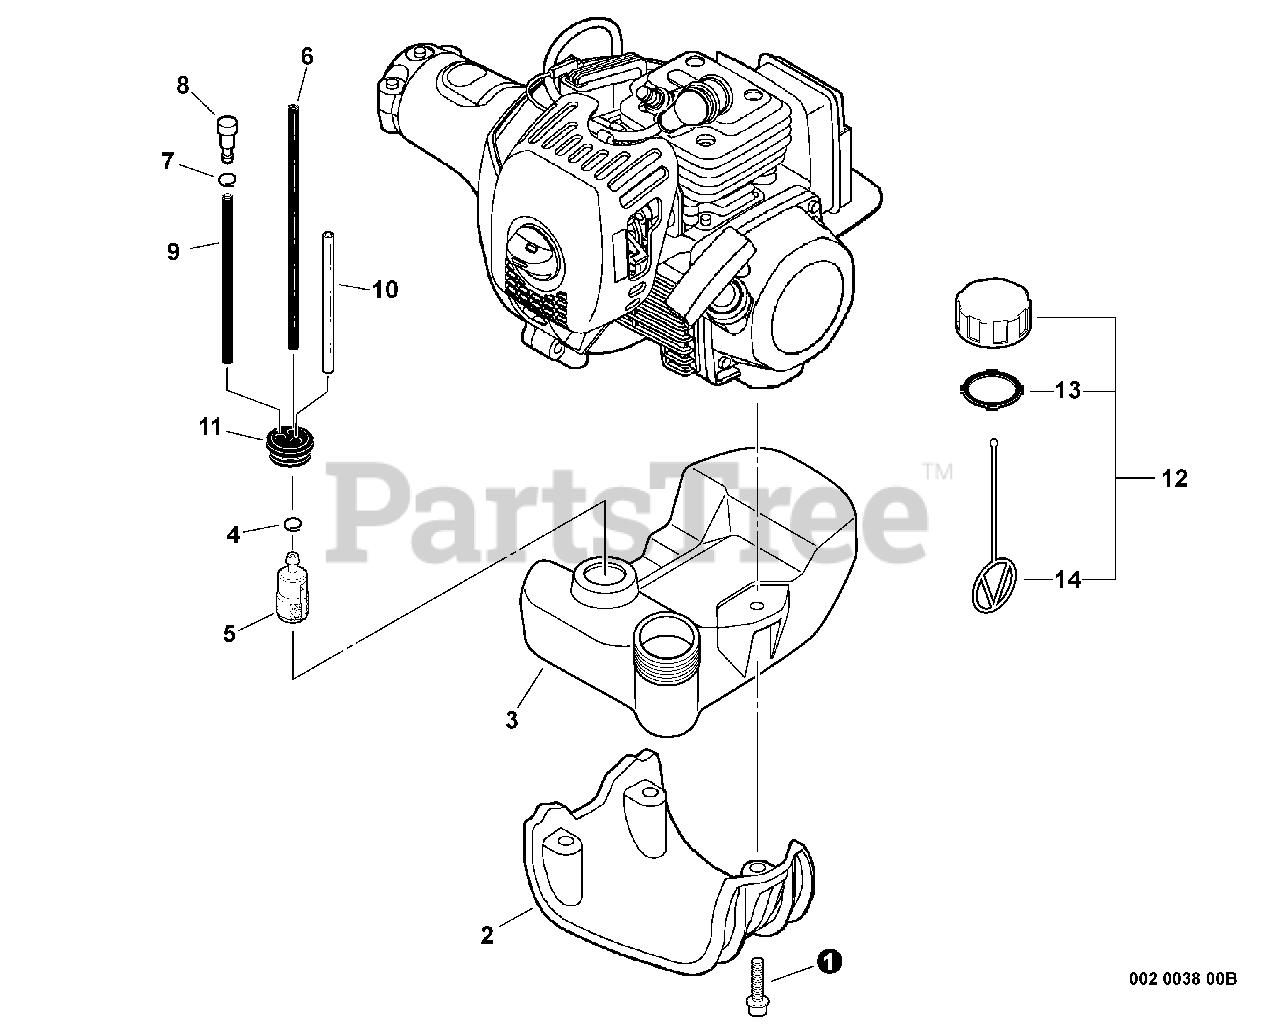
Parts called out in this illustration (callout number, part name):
1	BOLT 5×20
2	GUARD, FUEL TANK
3	TANK, FUEL
4	CLIP 6 MM
5	FILTER, FUEL 125-528
6	PIPE, FUEL 3×5×195 BLACK
7	CLIP Ø6.5 MM
8	VENT ASSY
9	PIPE 3×6×115 BLACK
10	PIPE, FUEL 3×6×80 CLEAR
11	GROMMET, FUEL
12	CAP ASSY, FUEL
13	GASKET, FUEL CAP
14	CONNECTOR, CAP L= 100 MM
